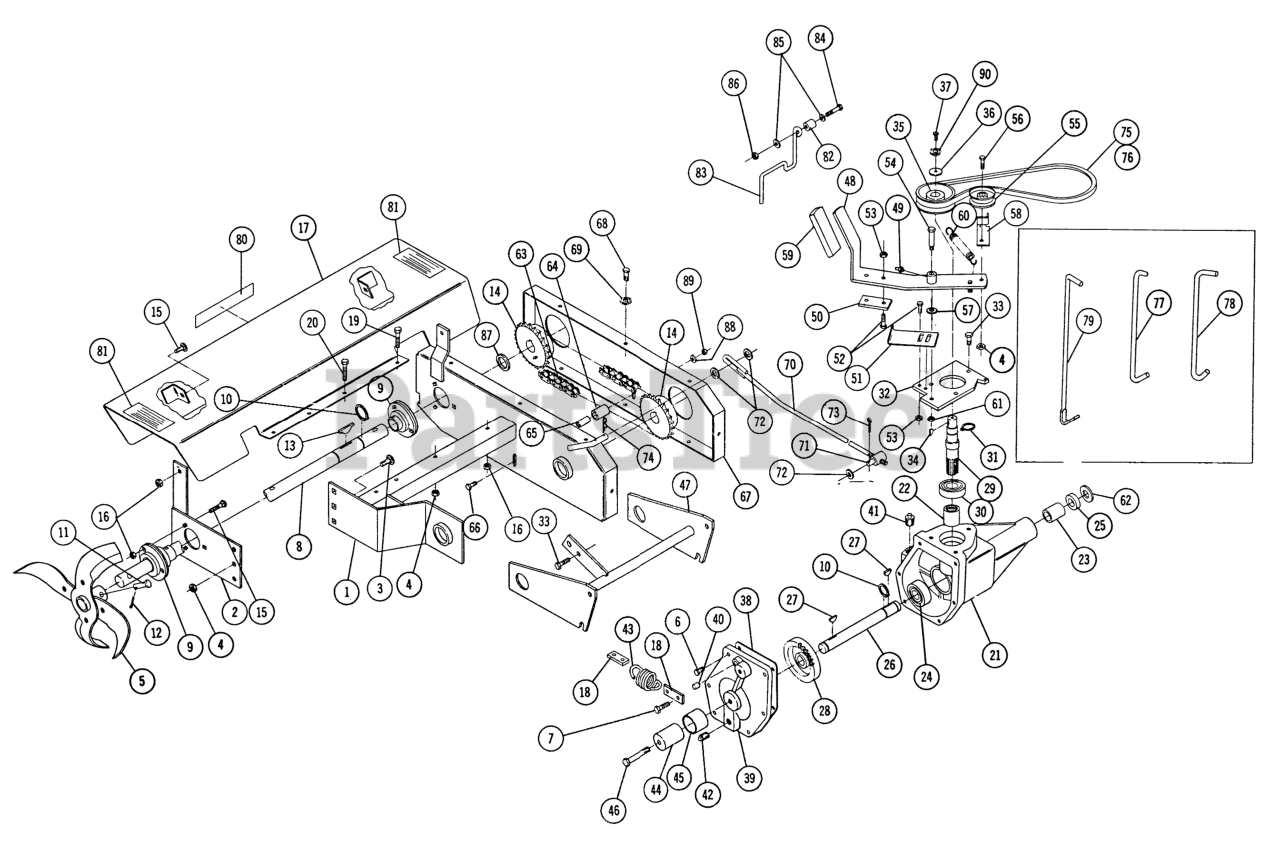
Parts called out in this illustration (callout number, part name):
1	Frame
2	Support
3	Bolt 3/8-16 x 1
4	3/8-16 E.S.
5	Tine
6	Bolt, 3/8-16 x 1
7	Bolt 3/8-16 x 1 1/4 Nylok
8	Shaft-Tine
9	Bearing-Flanged Mounted
10	Snap Ring
11	Clevis Pin
12	Cotter Pin
13	Key-Hi-Pro #806
14	Sprocket
15	Bolt Hex 5/16-18 x 3/4
16	Nut 5/16-18
17	Tine-Shield
18	Plate
19	Bolt, 5/16-18 x 3
20	Bolt Hex 3/8-16 x 1
21	Case-Gear
22	Bearing-Axle
23	Bearing-Bronze
24	Ball Bearing
25	Seal
26	Shaft-Output
27	Key-Hi-Pro #806
28	Gear-Spiroid
29	Gear-Pinion Spiroid
30	Ball Bearing
31	Snap Ring-External
32	Cap-Gear Box
33	Bolt 3/8-16 x 7/8
34	Key-Hi-Pro #606
35	Pulley-Drive
36	Washer-Special
37	Bolt-1/4-20 x 5/8
38	Gasket-Gear-Case
39	Cover-Gear-Case
40	Breather
41	Plug
42	Plug-Pipe 1/4-18
43	Spring-Stop
44	Pivot Frame Mounting
45	Spacer
46	Bolt-Hex 1/2-13 x 3
47	Mounting Plate
48	Idler Arm
49	Zerk
50	Plate-Wear
51	Bracket-Clutch Adjustment
52	Bolt 1/4-20 X 3/4
53	Nut, 1/4-20
54	Bolt-Shoulder
55	Idler Pulley
56	Bolt Hex 3/8-16
57	Washer
58	Bracket-Belt Guard
59	GRIP
60	SPRING IDLER
61	3/8-16 Jam Nut
62	Gear-36T
63	Chain-Drive
64	Roller-Chain Support
65	Spacer-Chain Support
66	Bolt-Carriage
67	Cover-Case-Chain
68	Bolt Hex 5/16-18
69	Lockwasher
70	Rod-Hitch
71	ROD-TRUNNION LIFT
72	Washer
73	Cotter Pin
74	Hairpin
75	V-BELT
76	BELT TIL DR MECH
77	Rod-Tiller Hanger
78	Rod-Mower Hanger
79	Rod-Mower Hanger
80	Decal-Wheel
81	Decal-Caution
82	Spacer-Mech. Trans. Tractors Only
83	Guide-Belt
84	Bolt 1/4 20 x 1 1/4
85	Washer
86	Nut-Nylok
87	Spacer tine Shaft
88	Lockwasher
89	3/8-16 Jam Nut
90	Lockwasher
